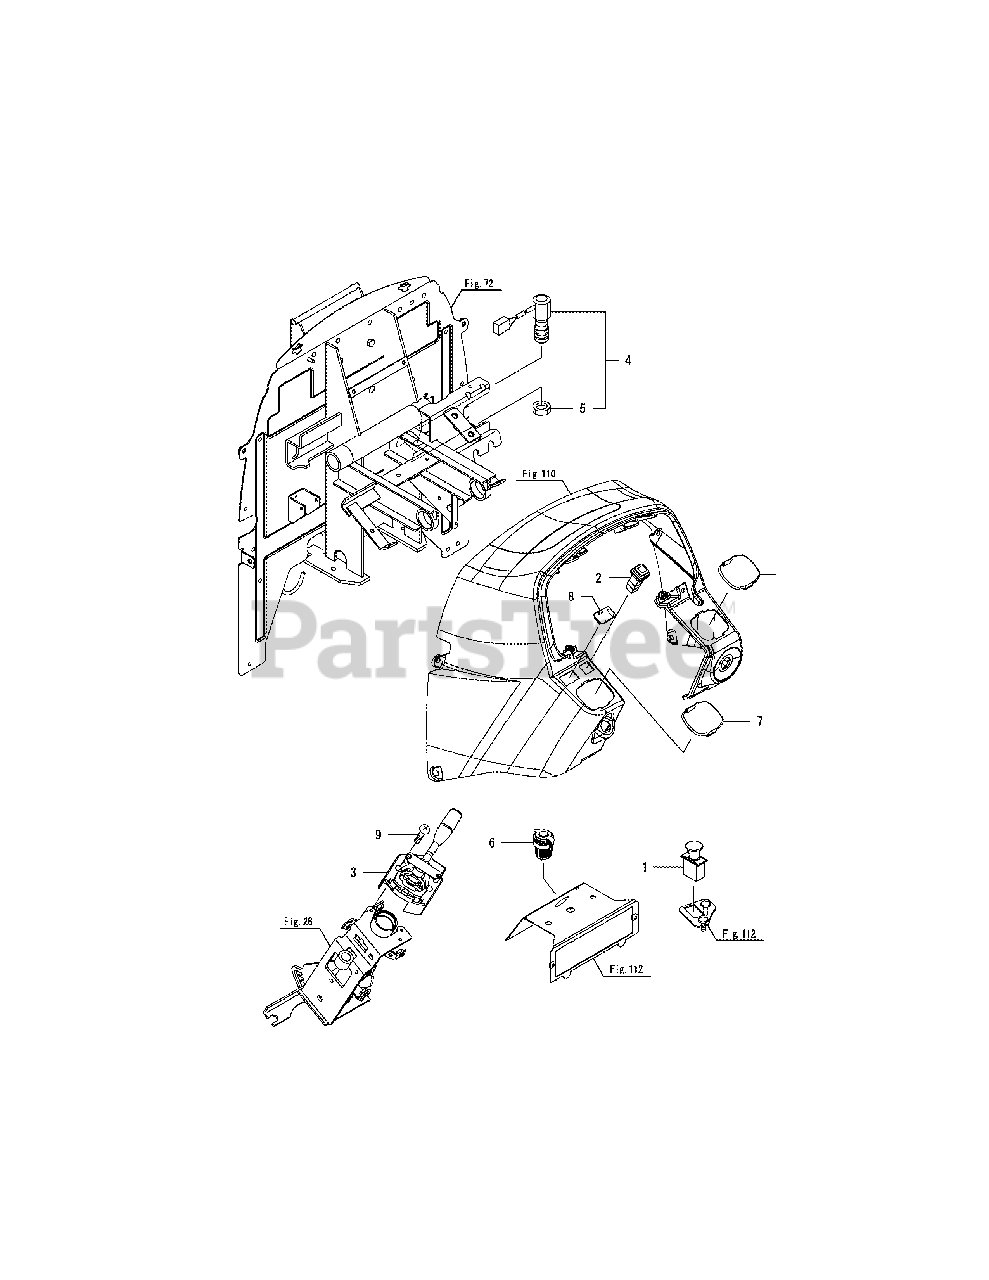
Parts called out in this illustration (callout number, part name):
3	SW, LEVER COMBINATION
4	SWITCH, BRAKE LAMP
5	LOCK NUT M12 PLATED
6	DC POWER OUTLET
7	COVER, SW-NONE
